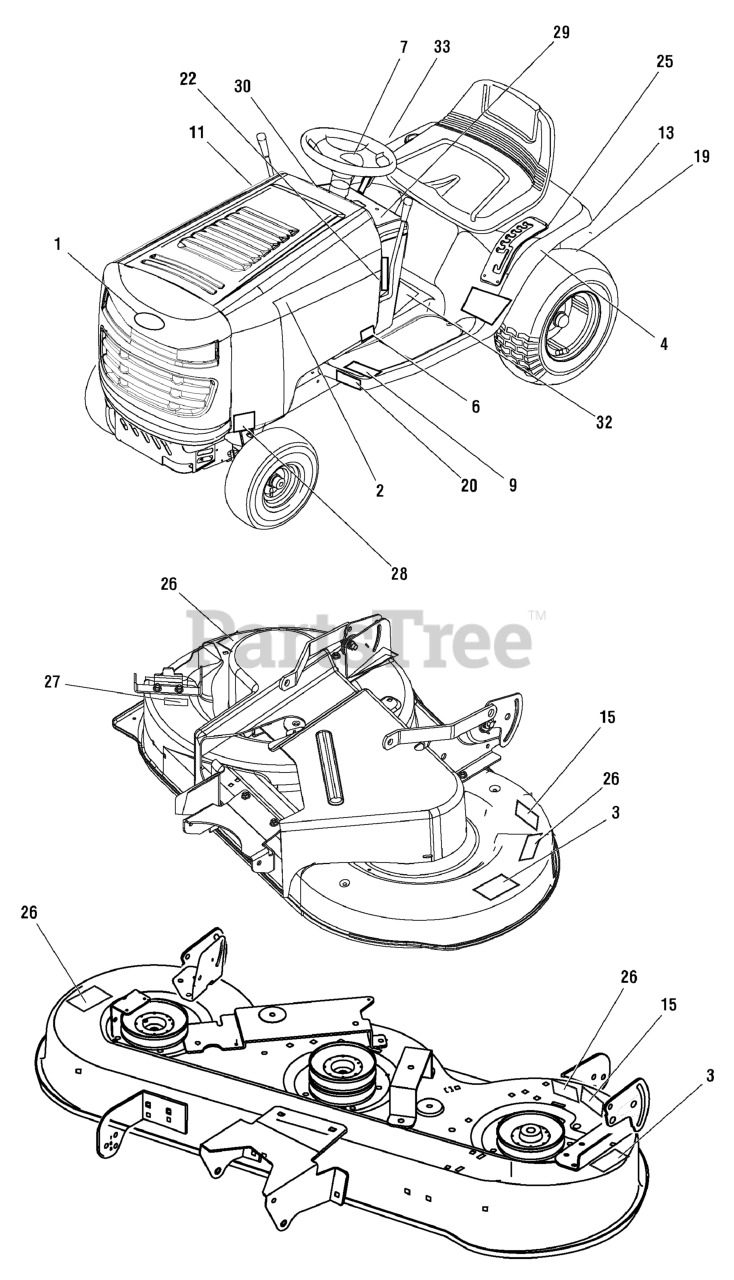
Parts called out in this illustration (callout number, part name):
1	DECAL, Hood
2	DECAL, Performer
3	DECAL, Deck Width, 107 cm, 42"
3	DECAL, Deck Width, 117 cm, 46"
4	DECAL, 12.5/96
4	DECAL, 15.5/107
4	DECAL, 17.5/117
6	DECAL, 12.5HP I/C
6	DECAL, 15.5HP I/C
6	DECAL, 17.5HP Intek
7	DECAL, Steering Wheel
9	DECAL, Belt/ Clutch
11	DECAL, Cut Height, 7 Position
13	DECAL, Roll Release
15	DECAL, No Step
19	DECAL, Weight Limitation
20	DECAL, Drive Pedal
22	DECAL, Gas Gauge
22	DECAL, Fuel Gauge Long
25	DECAL, Deck Level
26	DECAL, Deck Symbols, International
27	DECAL, Warning, Pinch Point
28	DECAL, Heat Shield Warning
29	DECAL, Dash / Symbols X-W Styles
30	DECAL, Dash/ Symbols
32	DECAL, Tunnel Cover Warnings
33	DECAL, 5 Speed
